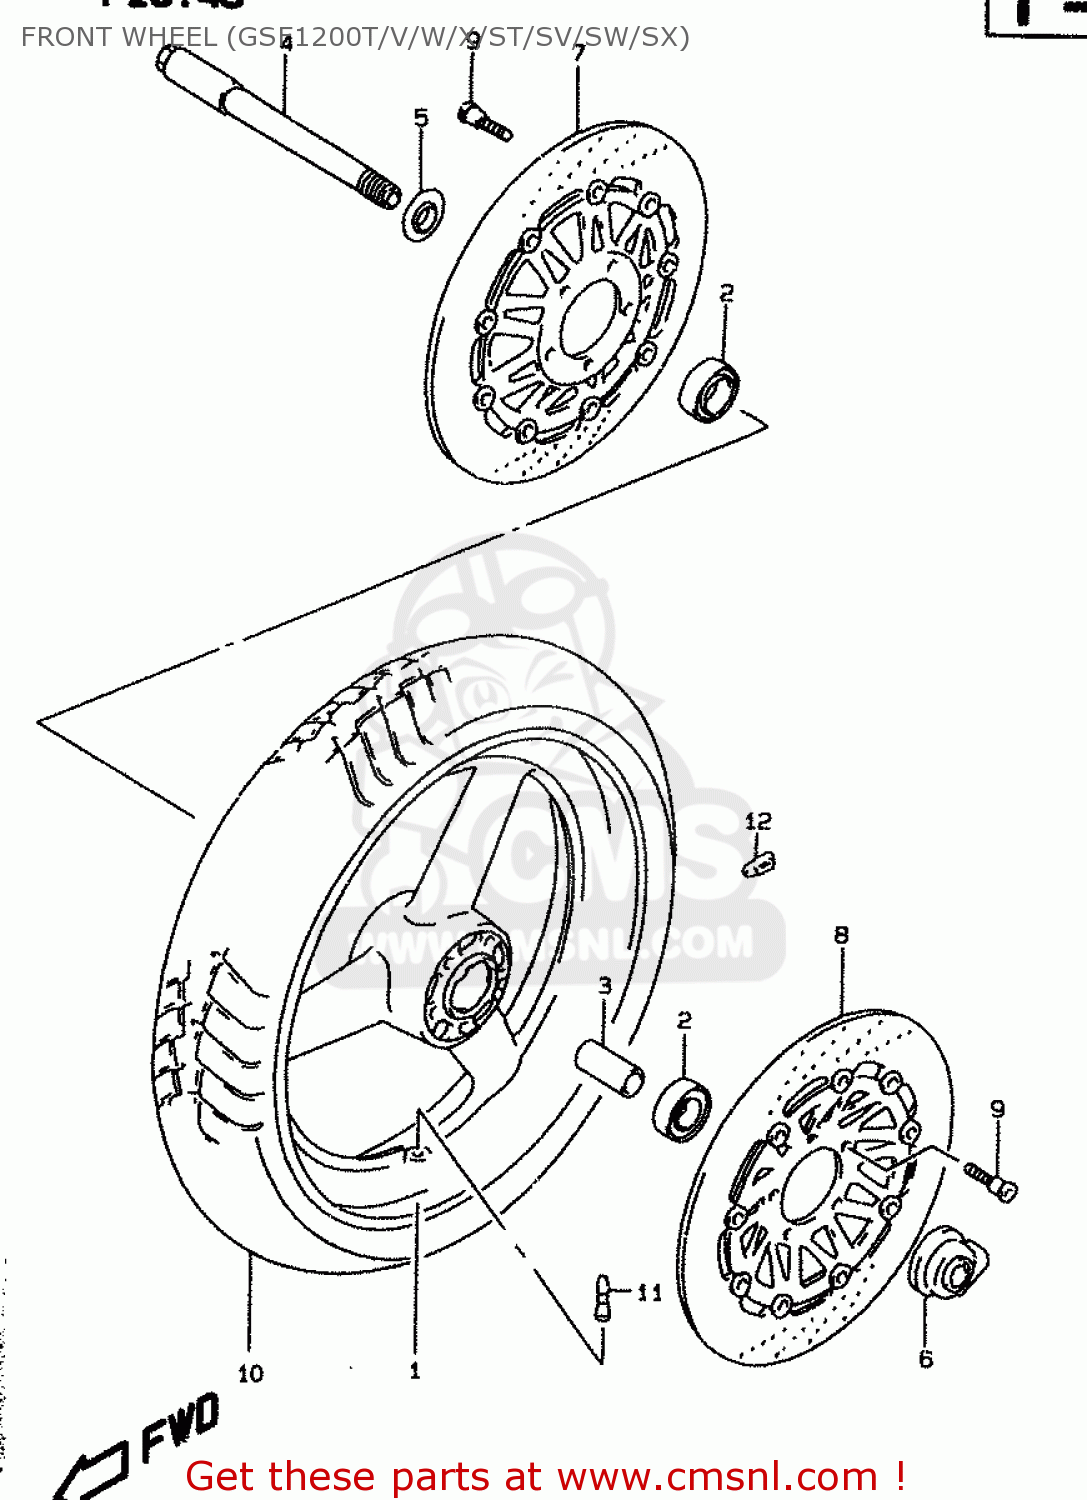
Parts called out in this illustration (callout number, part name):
1	WHEEL,FRONT (MT3.50X17)
2	BEARING
3	SPACER(20.8X27.2X74)
4	AXLE,FR
5	SPACER,FR HUB BEARING,R
6	BOX ASSY,SPEEDOMETER GEAR
7	DISC,FR BRAKE,R
8	DISC,FR BRAKE,L
9	BOLT 8X33
10	TIRE,FRONT 120/70 ZR17
11	VALVE ASSY,WHEEL RIM(TR412)
12	BALANCER,WHEEL (10G)
